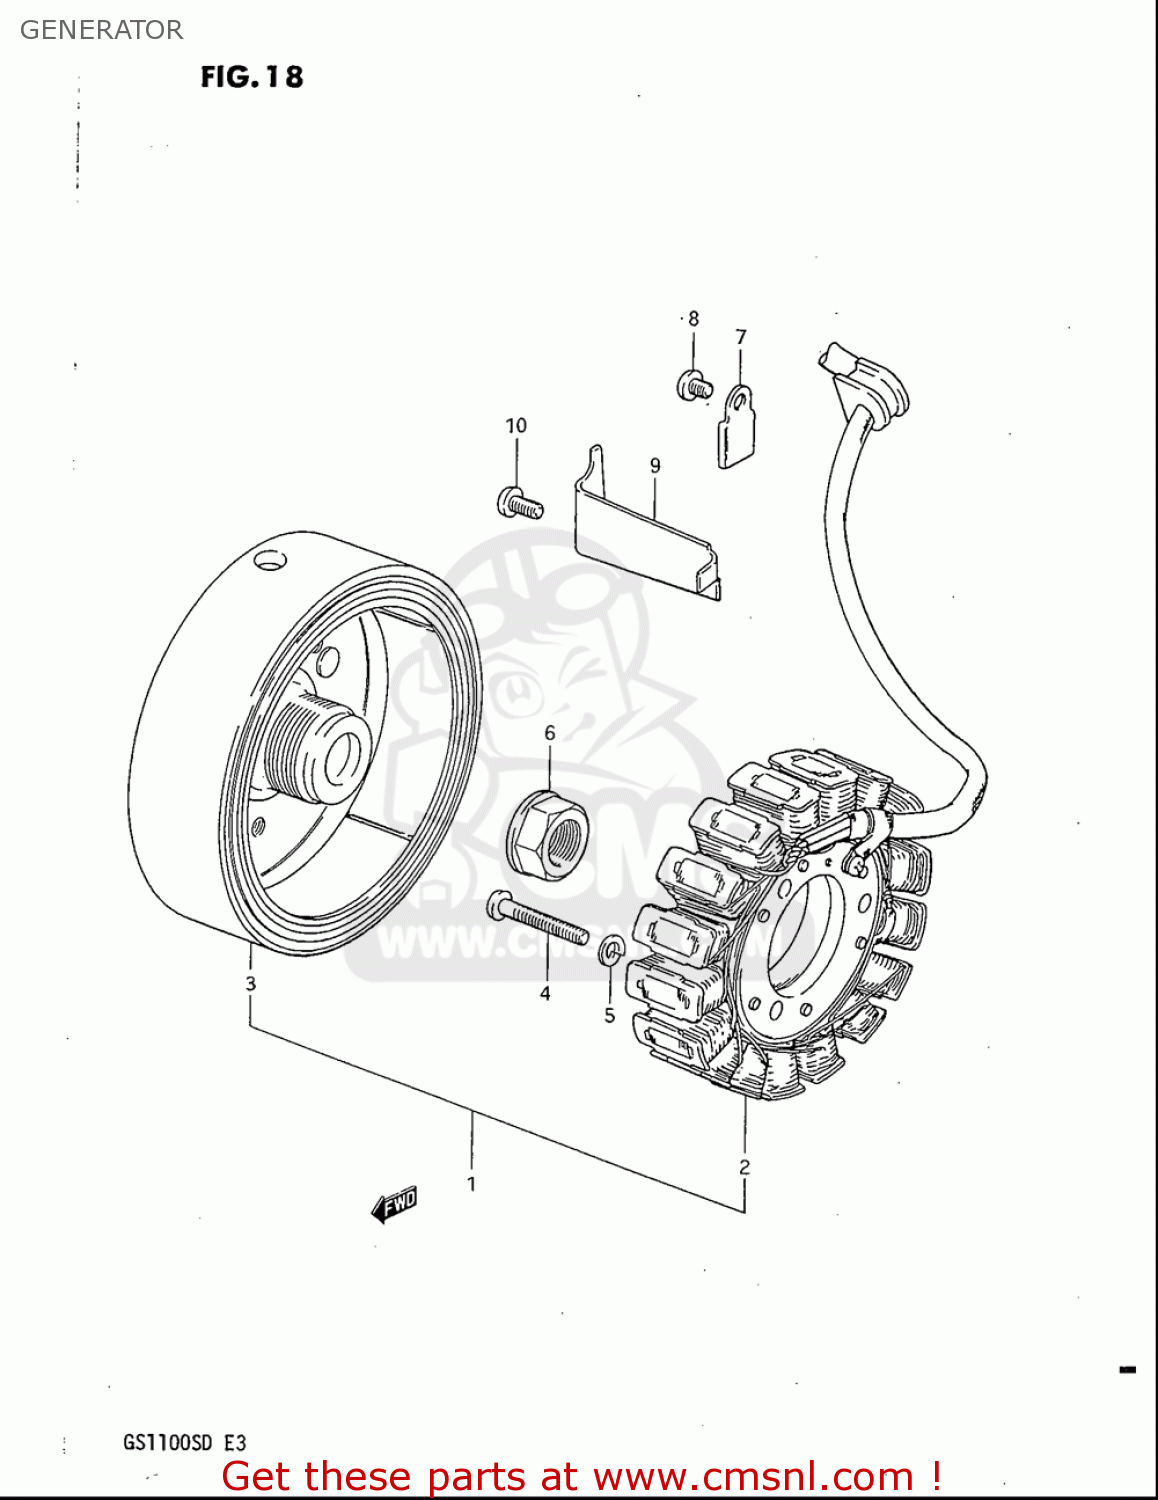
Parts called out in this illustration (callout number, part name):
1	STATOR
2	STATOR
3	ROTOR ASSY
4	SCREW
5	WASHER,LOCK
6	NUT,GENERATOR ROTOR
7	CLAMP,GENERATOR LEAD WIRE
8	SCREW
9	CLAMP,GENERATOR LEAD WIRE
10	SCREW
